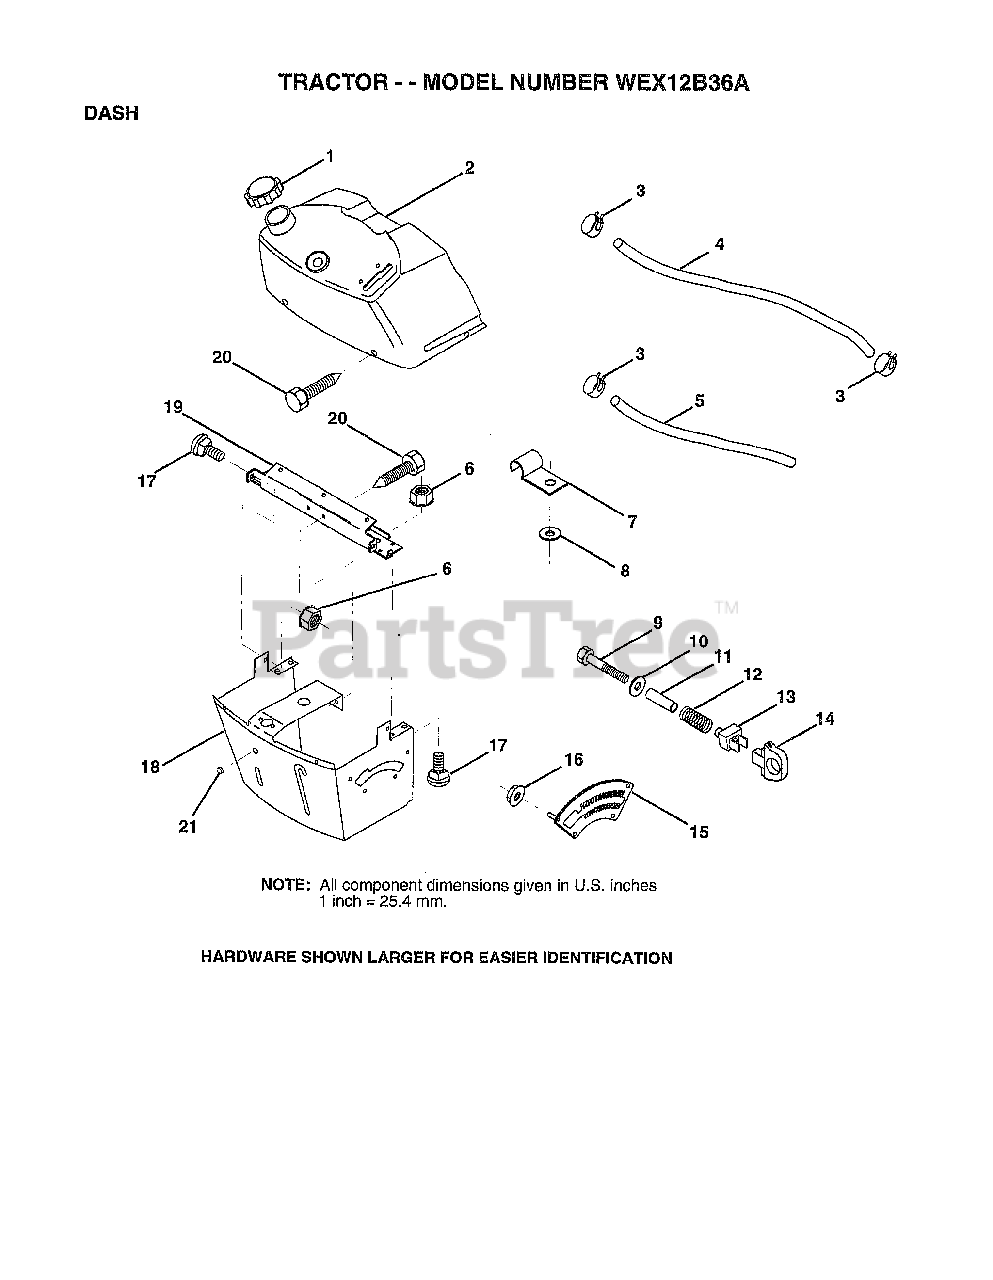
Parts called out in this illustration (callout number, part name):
1	CAP BLK FUEL LR
2	TANK.ASM.DASH.LR
3	HOSE CLAMP
5	FUEL LINE T
6	NUT HXKEP 1/4X20
7	CLIP T
8	WASHER PM
9	BOLT
11	SPACER SPLIT
12	SPRING M
13	"KNOB,HGT RETAINER"
14	KNOB
15	ADJUSTER QUAD
16	NUT
17	BOLT
18	SUPT ASSY DASH
19	CROSS BRACE
20	SCREW.1/4-20X1/2
21	PLUG DOME
